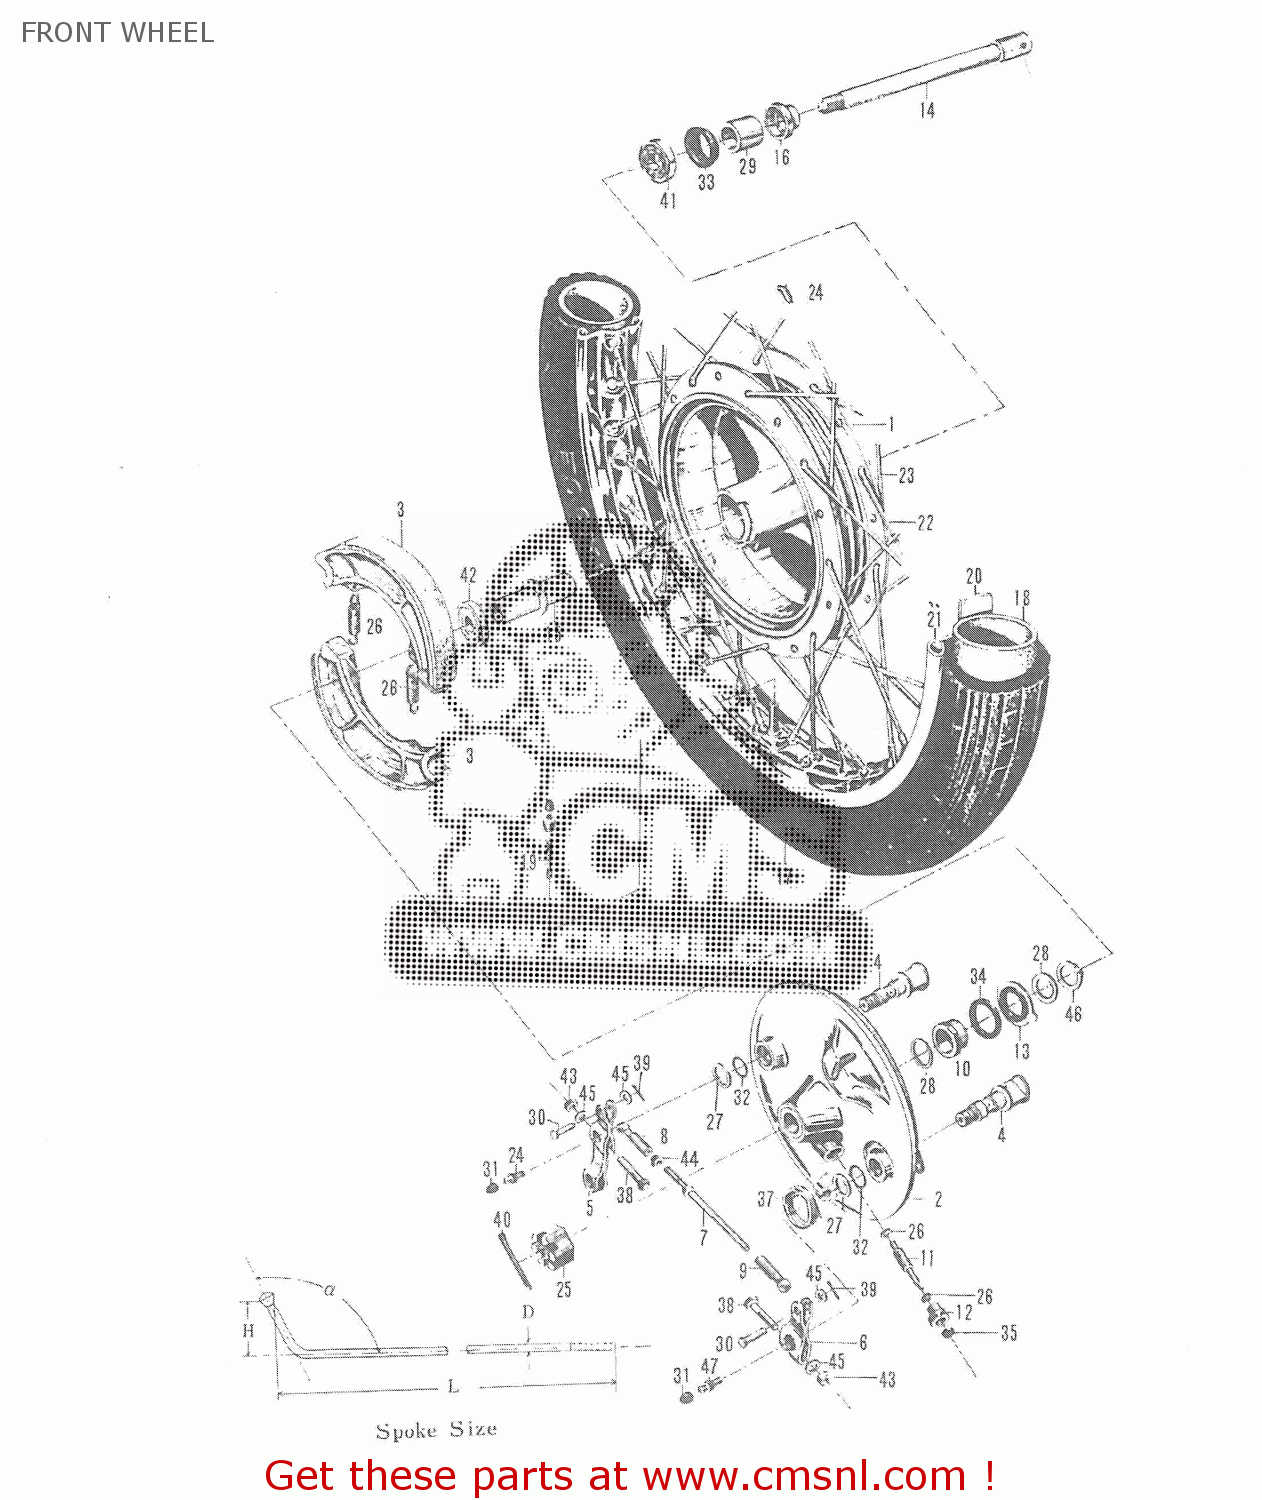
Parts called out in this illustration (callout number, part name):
1	HUB,FRONT
2	PANEL,FRONT HUB
3	SHOE,BRAKE
4	CAM,FRONT BRAKE
5	LEVER,FRONT BRAKE CAM
6	LEVER,FRONT BRAKE CAM
7	BRAKE CAM LEVER CONNECTING ROD
8	BRAKE CAM LEVER CONNECTING ROD FRONT END PIECE
9	BRAKE CAM LEVER CONNECTING ROD REAR END PIECE
10	GEAR,SPEEDOMETER
11	PINION,SPEEDOMETER
12	BUSHING,SPEEDOMETER PINION
13	DRIVER,SPEEDOMETER GEAR
14	FRONT AXLE
15	SPACER,FRONT HUB BEARING
16	SPACER,FRONT HUB BEARING
17	TIRE,FRONT
18	TUBE,INNER
19	VALVE,INNER TUBE
20	PROTECTOR,INNER TUBE
21	RIM,FRONT WHEEL
22	SPOKE,WHEEL
23	SPOKE,WHEEL
24	NIPPLE,SPOKE
25	NUT
26	WASHER (5.1X9X0.4)
27	WASHER (15X24X1.6)
28	WASHER(22.5X27X1)
29	SPACER
30	PIN
31	GREASE NIPPLE CAP
32	O-RING,BOSS
33	OIL SEAL
34	OIL SEAL
35	SEAL,OIL(6X10X3)
36	SPRING
37	SPRING
38	HEXAGON BOLT
39	COTTER PIN
40	COTTER PIN
41	BEARING
42	BEARING
43	HEXAGON NUT
44	HEXAGON NUT
45	FLAT WASHER
46	CIRCLIP
47	GREASE NIPPLE
